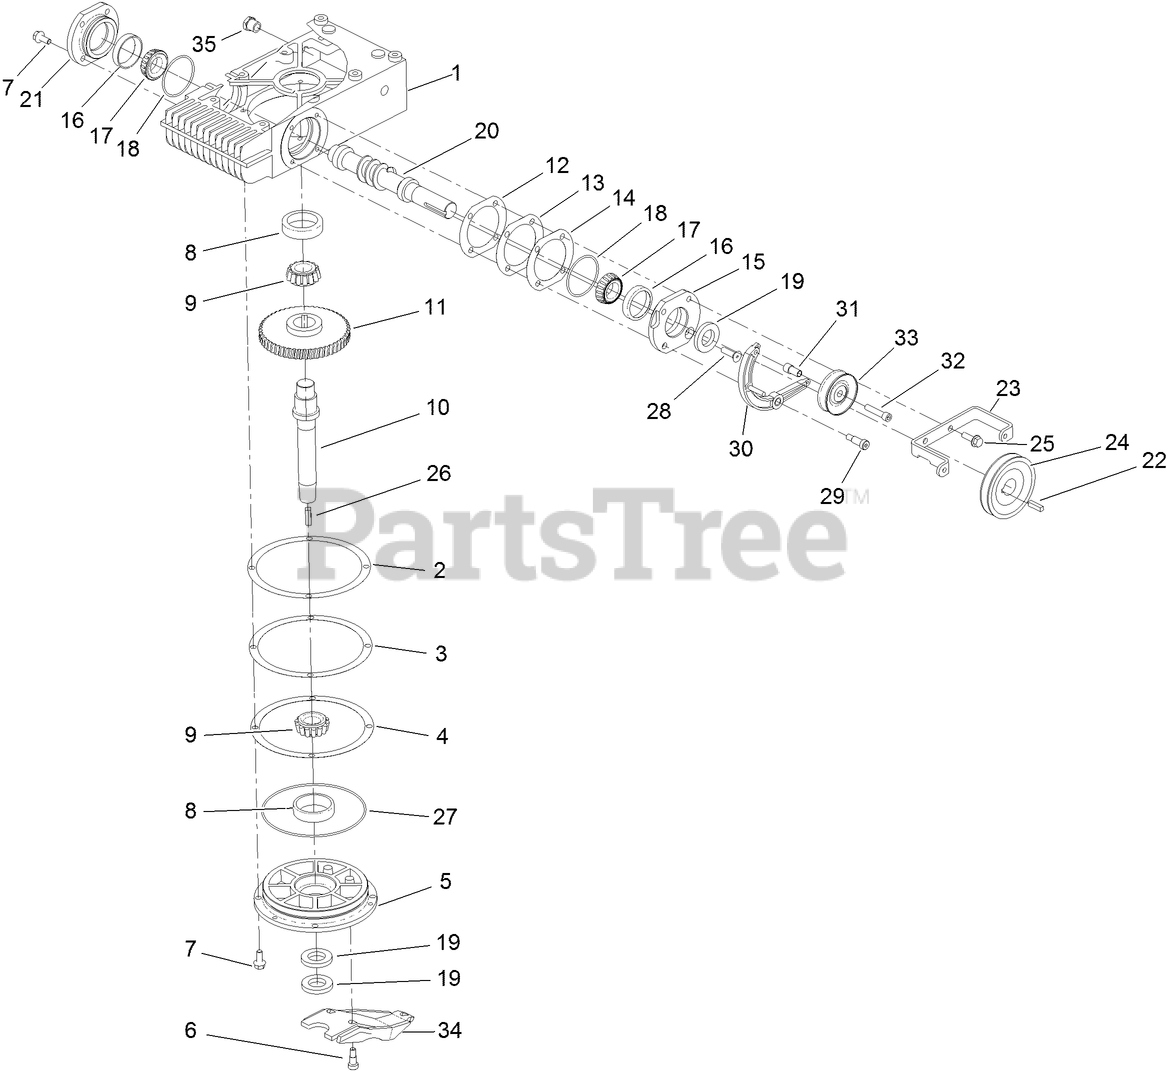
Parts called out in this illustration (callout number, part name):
1	GEARCASE
2	SHIM-COVER, BOTTOM (.001 INCH)
3	SHIM-COVER, BOTTOM (.005 INCH)
4	SHIM-COVER, BOTTOM (.010 INCH)
5	CAP-BEARING, BOTTOM
6	SCREW-HSBH
7	SCREW-HHF
8	BEARING-CUP
9	BEARING-CONE
10	SHAFT-OUTPUT
11	GEAR-WORM
12	SHIM-COVER, SIDE (.001 INCH)
13	SHIM-COVER, SIDE (.005 INCH)
14	SHIM-COVER, SIDE (.010 INCH)
15	COVER-BEARING, SHEAVE END
16	BEARING-CUP, TAPERED
17	BEARING-CONE, TAPERED
18	O-RING
19	SEAL-SHAFT
20	SHAFT-INPUT
21	COVER-BEARING, BLIND END
23	BRACKET-GUARD, BELT
24	SHEAVE
25	SCREW-HHF
26	KEY-HARDENED
27	O-RING
28	SCREW
29	SCREW-SHOULDER, HSH
30	CLUTCH LEVER ASM
31	SPACER-IDLER, TROWEL
32	SCREW-HSH
33	IDLER-V, TROWEL
34	LEVER-TILT
35	PLUG-SIGHT, OIL
